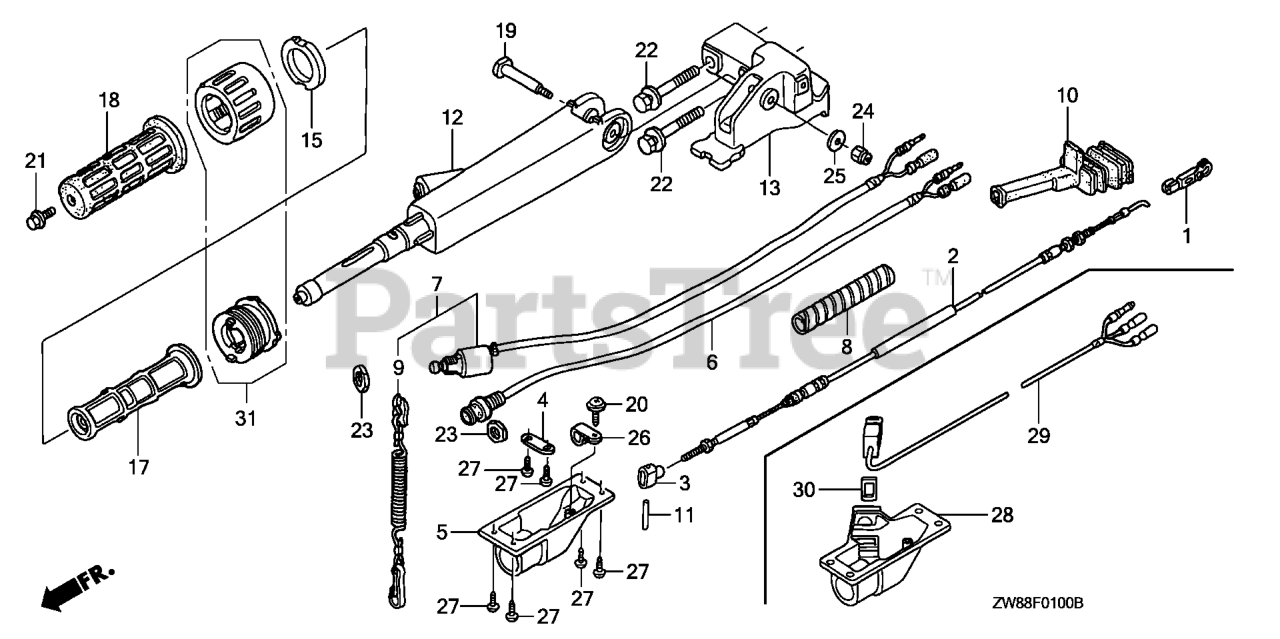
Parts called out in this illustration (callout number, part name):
1	LINKAGE, PIVOT
2	CABLE, THROTTLE
3	PIVOT, THROTTLE CABLE
4	PLATE, SHIFT
6	SWITCH ASSY., STARTER
7	SWITCH ASSY., EMERGENCY STOP
8	TUBE, SPIRAL B
9	WIRE, EMERGENCY DUAL QTY = (2) (SINGLE)
10	GROMMET, OIL CASE (A)
11	PIN, THROTTLE CABLE
12	HANDLEBAR *NH246* (LOOSY GRAY)
13	BRACKET, HANDLEBAR *NH246* (LOOSY GRAY)
14	GRIP ASSY., THROTTLE FRICTION
15	PAD, THROTTLE FRICTION
16	GRIP ASSY., THROTTLE FRICTION
17	PIPE, GRIP
18	RUBBER, GRIP
19	SCREW, HANDLE PIVOT
20	SCREW, TAPPING (4X10)
21	BOLT, FLANGE (6X12) Use from Frame SN 1005249.
22	BOLT-WASHER (10X55)
23	NUT, HEX. (16MM) DUAL QTY = (2) (SINGLE)
24	NUT, SELF-LOCK (8MM)
25	WASHER (8MM)
26	CLIP, WIRE HARNESS (6.3MM)
27	SCREW, TAPPING (4X12)
28	COVER, SWITCH (PT)
29	SWITCH ASSY., POWER TILT
30	STAY, POWER TILT SWITCH
31	GRIP ASSY., THROTTLE FRICTION
